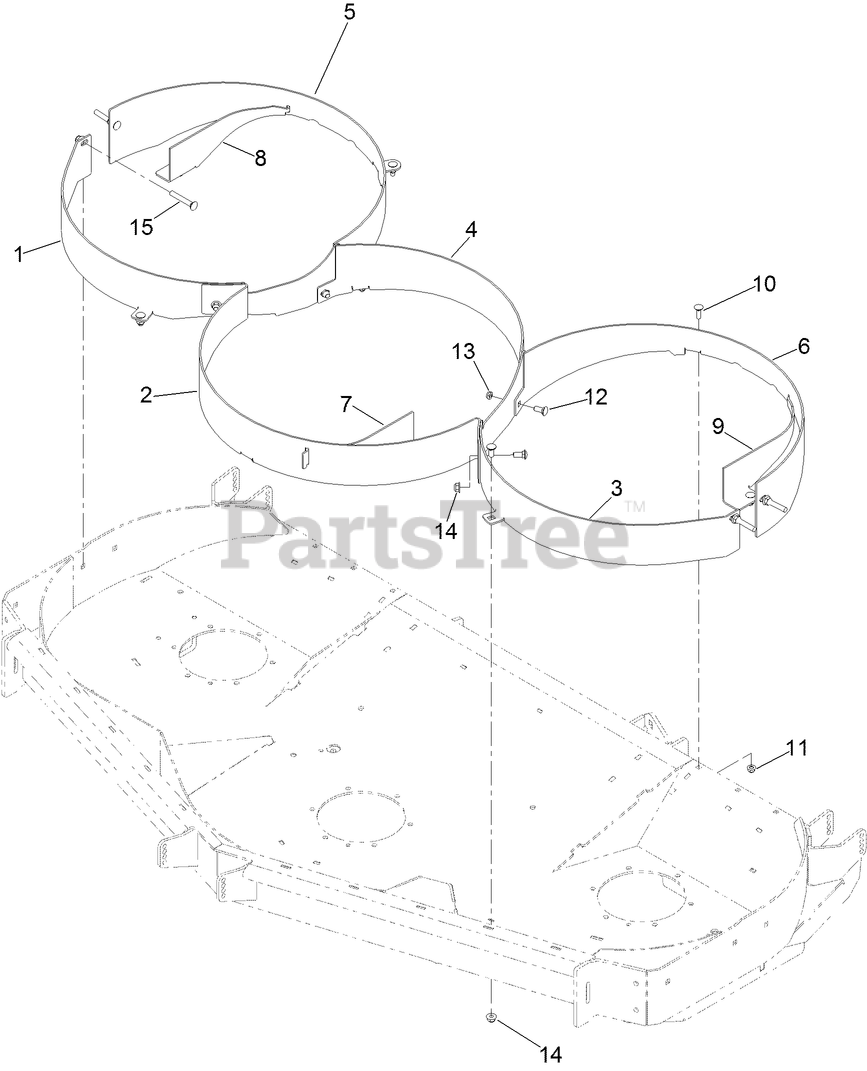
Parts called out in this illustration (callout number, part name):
1	BAFFLE-MULCH, FRONT RH
2	BAFFLE-MULCH, FRONT LH
3	BAFFLE-MULCH, FRONT CENTER
4	BAFFLE-MULCH, REAR LH
5	BAFFLE-MULCH, REAR RH
6	BAFFLE-REAR, CENTER
7	BAFFLE-KICKER, LH
8	BAFFLE-KICKER, FRONT CENTER
9	BAFFLE-KICKER, RH
10	BOLT-CARR
11	NUT-HF, NI
13	BOLT-CARR
14	NUT-HF, NI
15	SCREW-CARR
